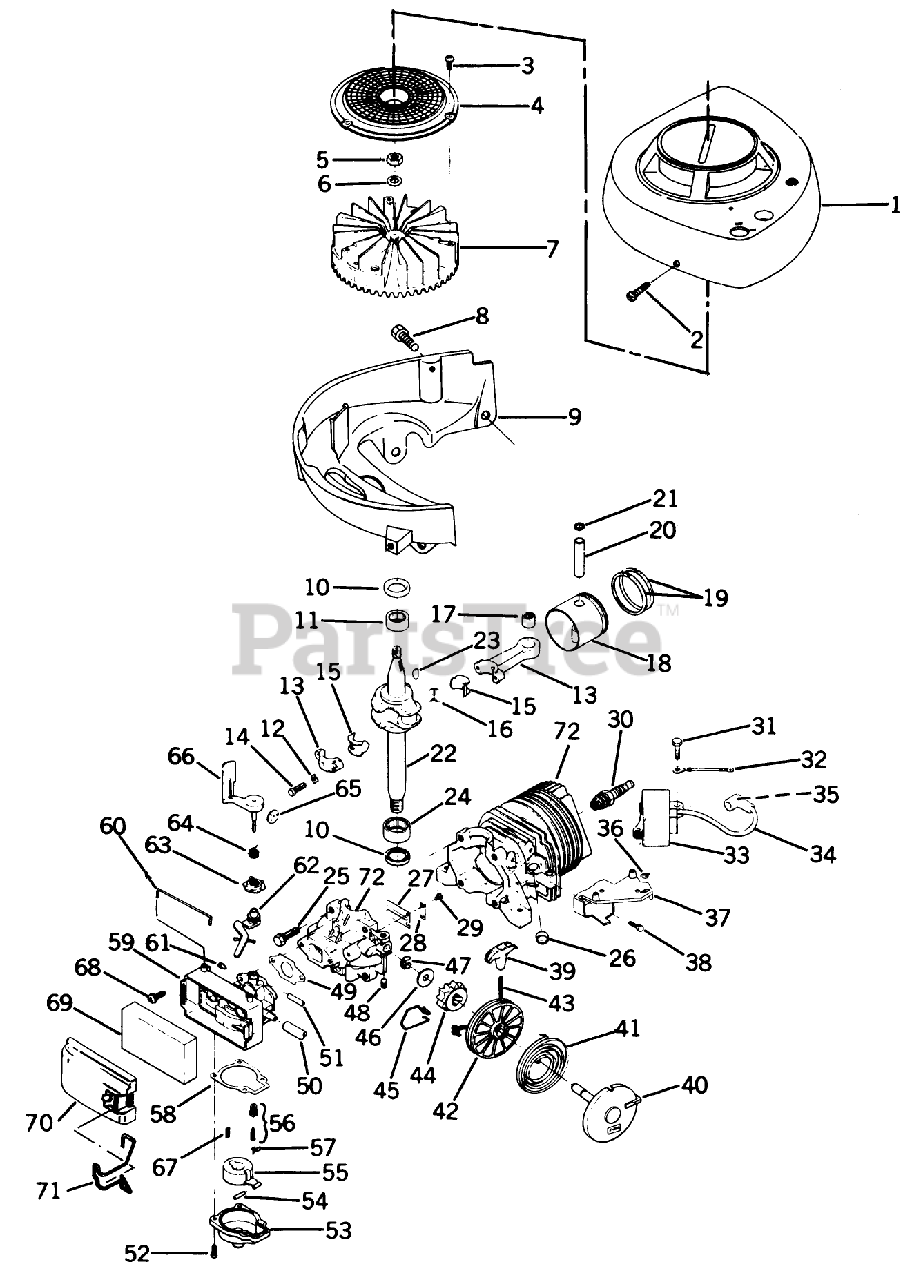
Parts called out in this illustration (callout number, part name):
2	SCREW F
5	NUT
8	SCREW-SEMS
11	BEARING V
14	SCREW
15	LINER ASM
17	BEARING AY F
20	Wrist Pin
21	RING-RETAINING
23	KEY
24	BEARING V
25	SCREW S
26	PLUG-CORE VF
28	PLATE-BACKUP, REED
34	HT LEAD&COVER XEV
36	NUT-CLIP
37	BRACKET S
39	HANDLE STARTER S
41	SPRING S
45	SPRING F
46	WASHER S
48	SET SCREW
49	GASKET CARB S
51	TUBING PRIMER S
52	SCREW-HH
60	RETAINER
61	F-SCREW CARB
62	LEVER
63	ADJUSTMENT COLLAR
64	SPRING
65	DISC S
68	SCREW
71	RETAINER-COVER, FILTER
